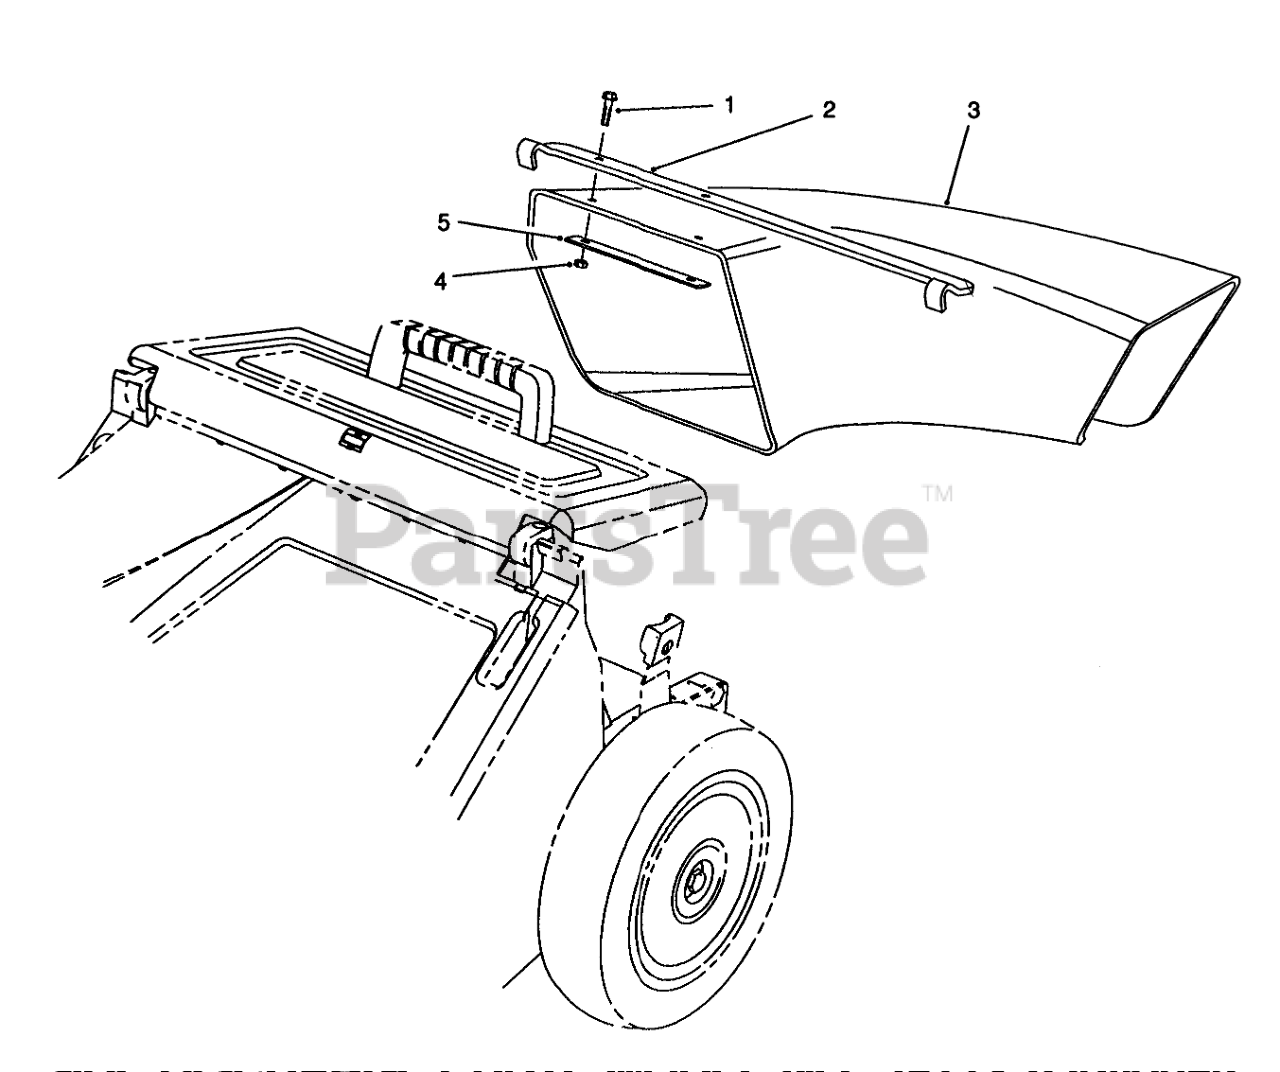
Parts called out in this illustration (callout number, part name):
1	SCREW-HWH
2	CHUTE HANGER BRACKET
3	Chute-Discharge
4	NUT-LOCK, NI
5	STRESS PLATE
